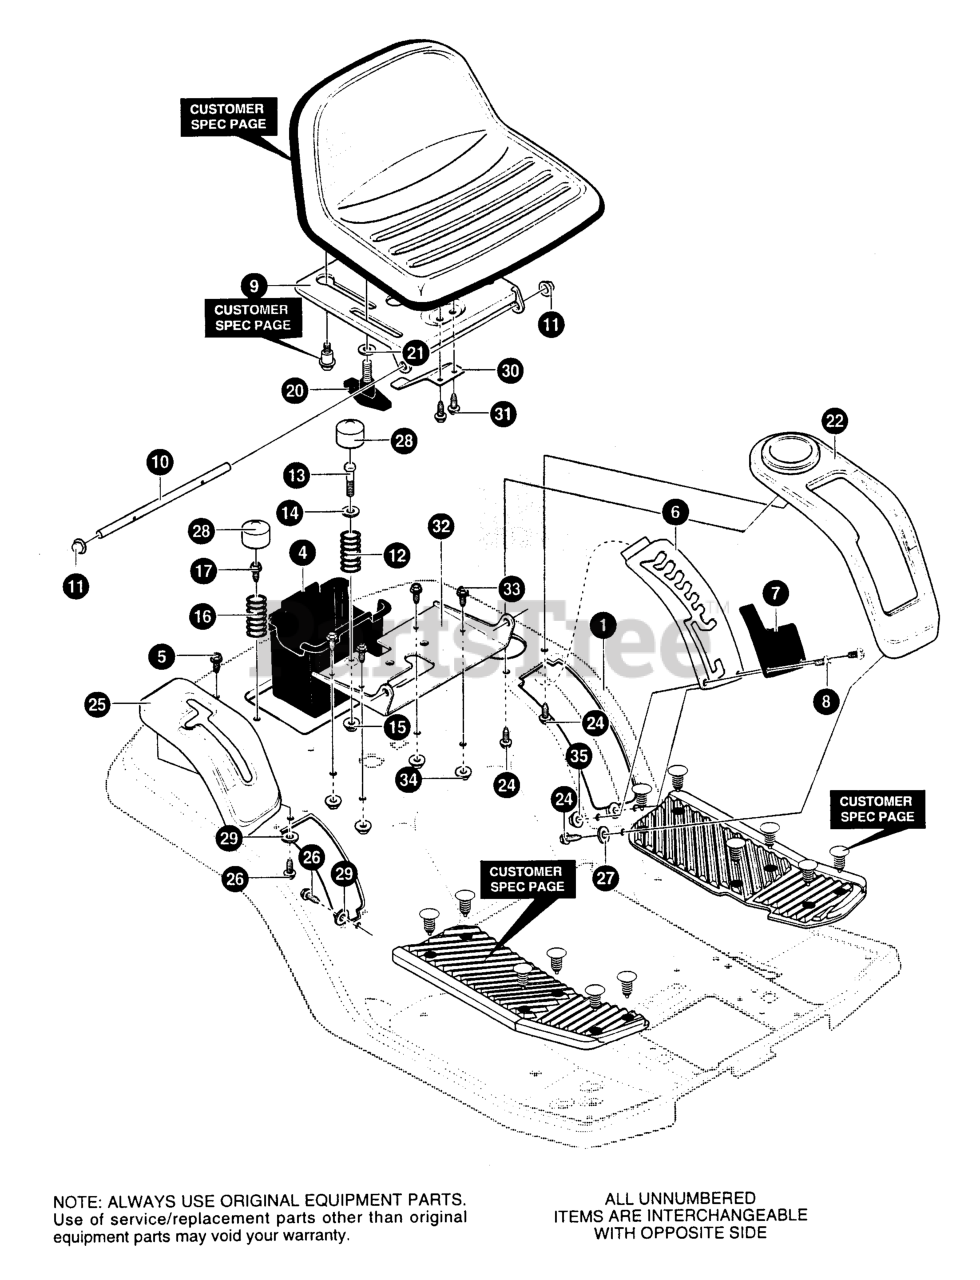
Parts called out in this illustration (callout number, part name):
1	SEAT DECK
4	CONTAINER, BATTERY
5	SCREW 1/4-20X.63 HHWATAPSER
6	PLATE, LIFT DETENT LG.
7	COVER, LIFT DETENT
8	SCREW,.230X.135 PPANTAP10-32B
9	SUPPORT, SEAT
10	HINGE SEAT PIVOT
11	NUT, PUSH CAP.375 (28X23)
12	SPRING, COMPRESS 4.57LGX1.17
13	BOLT, SHOULDER 1/4-20 NC-2A (9X55)
14	WASHER CUP ZINC
15	NUT, 1/4-20 WDFLLK
16	SPRING, COMPRESS 1.43LG 164X30
17	SCREW 5/16-18X.75 HHWATAPSGIB
20	BOLT, WING 5/16-18X.50 LG THRD
21	WASHER, FLAT .344X.62X.06
22	COVER,DETENT PLATE
24	SCREW, 1/4-15X.44/.53 HILOHHWA
25	COVER, MST SHIFT
26	SCREW, 1/4-15X.44/.53 HILOHHWA
27	FLATWASHER.286X.63X.065
28	CAP, HUB/SEAT SPRING
29	FLATWASHER.286X.63X.065
30	SPRING - LEAF
31	SCREW 1/4-20X.50 WAHHTAP
32	BRACKET, PIVOT SEAT
33	SCREW, 5/16-18 x .75 HHWATAP
34	SCREW, 10-24X.500TRSEGI
35	NUT, #10-32 CTRLK
